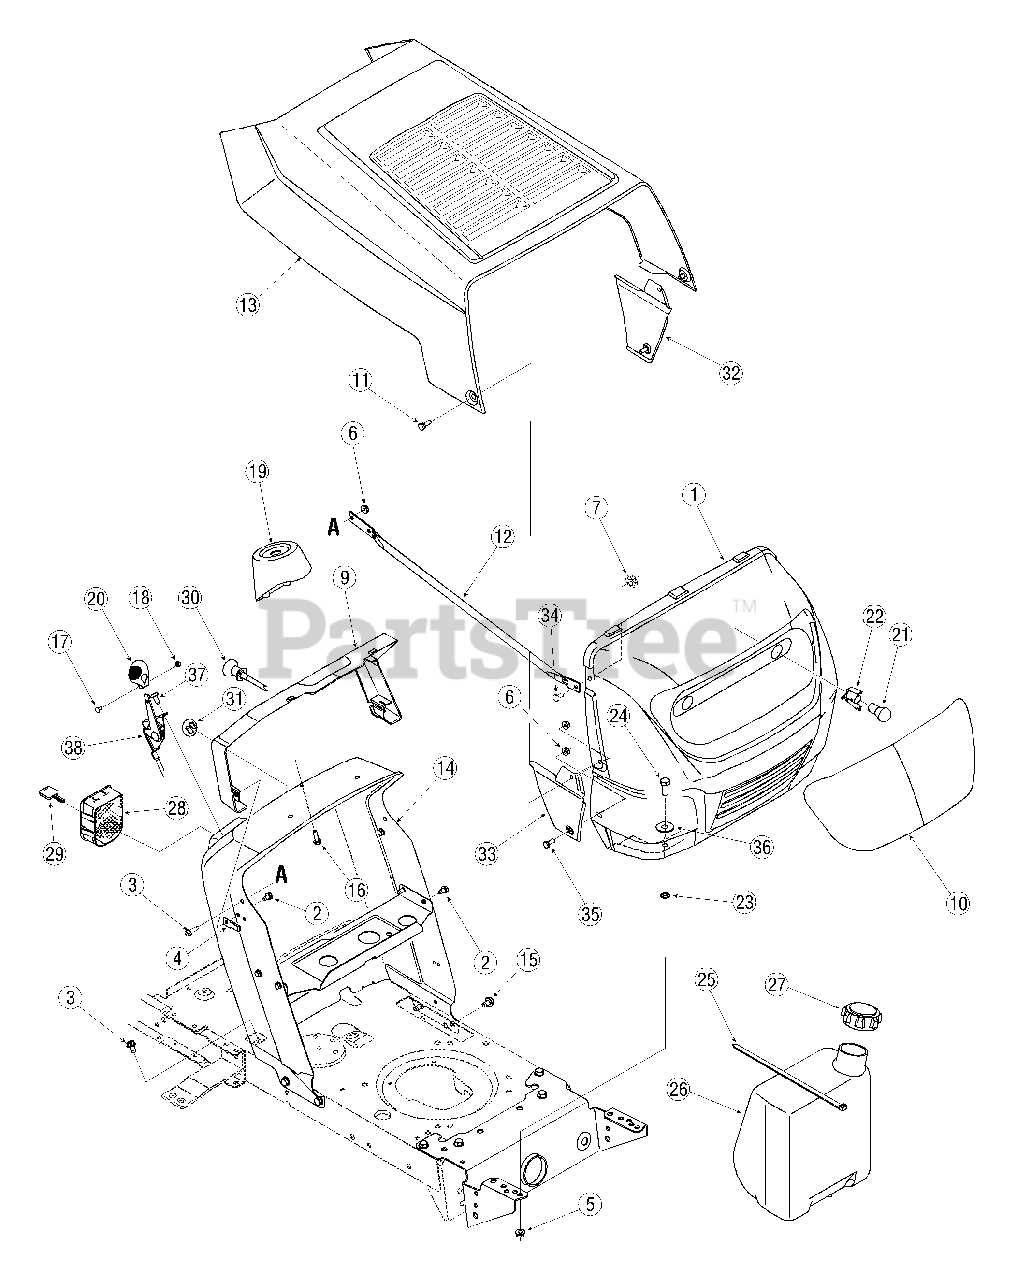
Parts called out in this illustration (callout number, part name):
2	Screw, 1/4-20, 0.500
3	Screw, 1/4-20, 0.750
4	Nut, 1/4-20, Speed U-type
5	Nut, Flange Lock, 5/16-18, Gr F, Nylon
6	Nut, Flange Lock, 1/4-20, Gr F, Nylon
7	Nut, Push-on, .25 Dia
8	Rivet, Flat Head 1/4"
9	Collar, Dash, 0-Style
10	Lens
11	Screw, Shoulder, .375 x .125, 1/4-20
16	Screw, 1/4-15, 0.750
17	Screw, Machine, #8-32, 0.375
18	Nut, Hex, #8-32, Gr A
19	Support, Steering
20	Knob, Control
21	Headlamp, 12V
22	Headlamp Socket
23	Speed Nut, .3125
24	Screw, 5/16-18, .750
25	Cable Tie, 34.75
26	Fuel Tank, 1.5 gal.
27	Fuel Tank Cap
28	Module, Ignition Switch
29	Key
30	Choke Control, 37.5"
35	Hex Screw, 1/4-20, .620
36	Flat Washer, .344 x .750 x .120
37	Screw, 1/4-14, .625
38	Throttle/Choke Control, 25"
